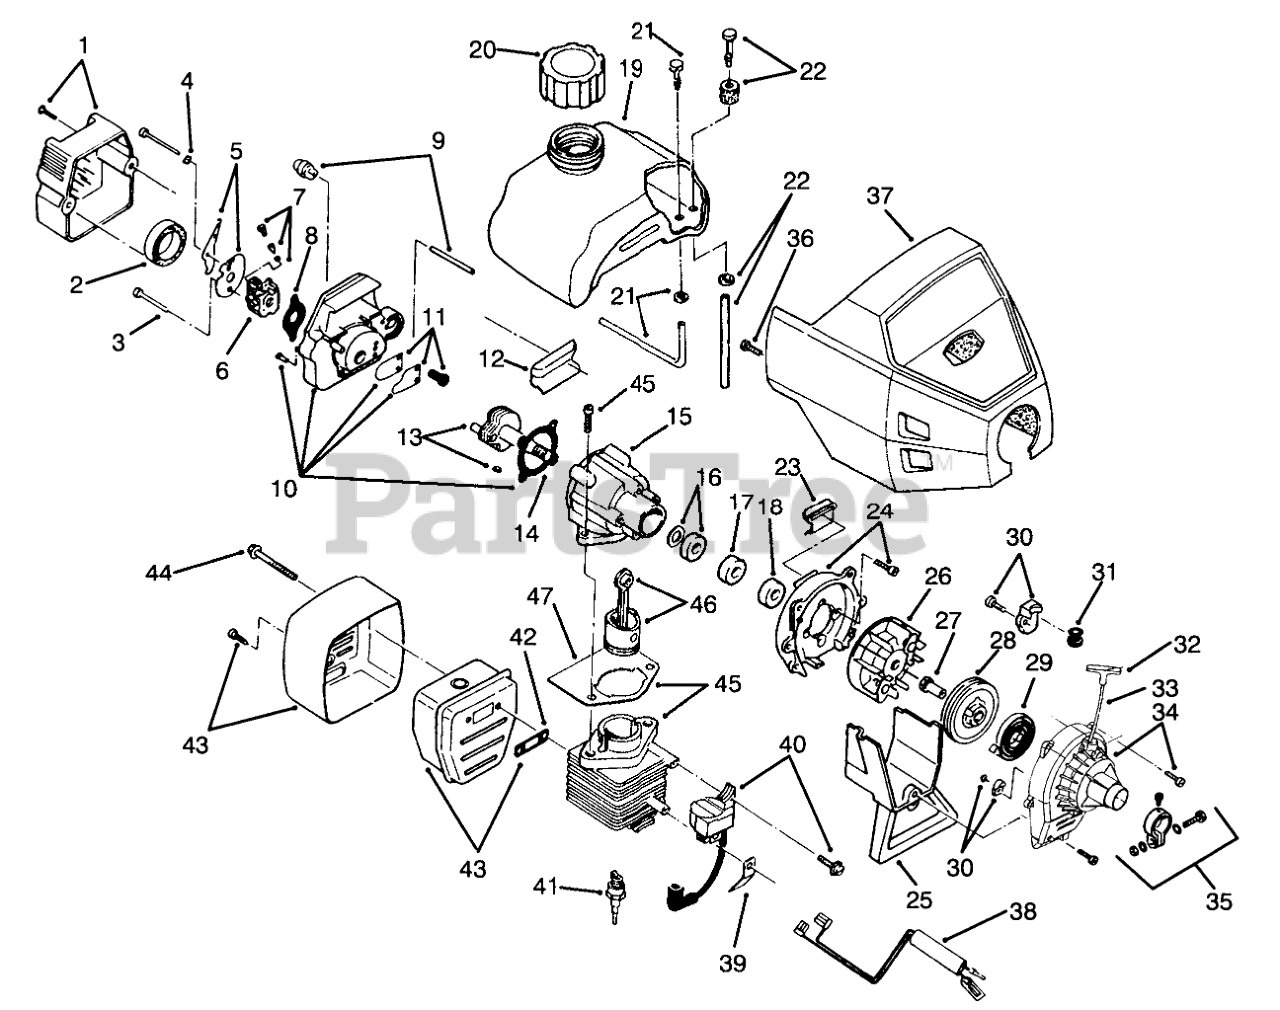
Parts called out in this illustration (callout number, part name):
1	Assy.-Carburetor/Air Clean. (Inc. Ref. No .2)
2	AIR CLEANER FILTER
3	CARB MTG SCREW ASM
4	WAVEY WASHER
5	CHOKE LEVER & PLATE
6	Carburetor
7	THROTTLE ADJ ASM
8	CARBURETOR GASKET(10 PER PACK)
9	PRIMER & HOSE ASM
10	Assembly-Carb. Mount (Incl. Ref. 11 & 12)
11	REED ASM
12	REAR MOUNTING PAD
13	POWER SHAFT ASM
14	CARB MT GASKET (10-PK)
15	Assy.-Crankcase (Incl. Ref. No. 14-18)
16	INNER BEARING ASM
18	OUTER BEARING
19	Assemby-Fuel Tank (Incl. Ref. No. 20-22)
20	FUEL CAP ASM
21	FUEL RETURN LINE ASM
22	FUEL LINE ASM
23	FRONT MOUNTING PAD
24	SHROUD ASM
25	Shroud Extension & Stand
26	Assembly-Flvwheel
27	SQUARE DRIVE NUT
28	RECOIL PULLEY ASM
29	RECOIL SPRING
30	Pulley Retainer Asm.
31	ROPE GUIDE
32	Handle-Pull
34	STARTER HSG ASM
35	CLAMP ASM - UPPER
36	ENGINE COVER SCREWS
37	ENGINE COVER ASM
38	LEAD WIRE ASM
39	GROUND TAB
40	Module Asm.
41	SPARK PLUG
42	Exhaust Gasket
43	MUFFLER ASM
44	MUFFLER MTG BOLT ASM
45	Throttle Lever
46	PISTON & ROD ASM
47	CYLINDER GASKET
